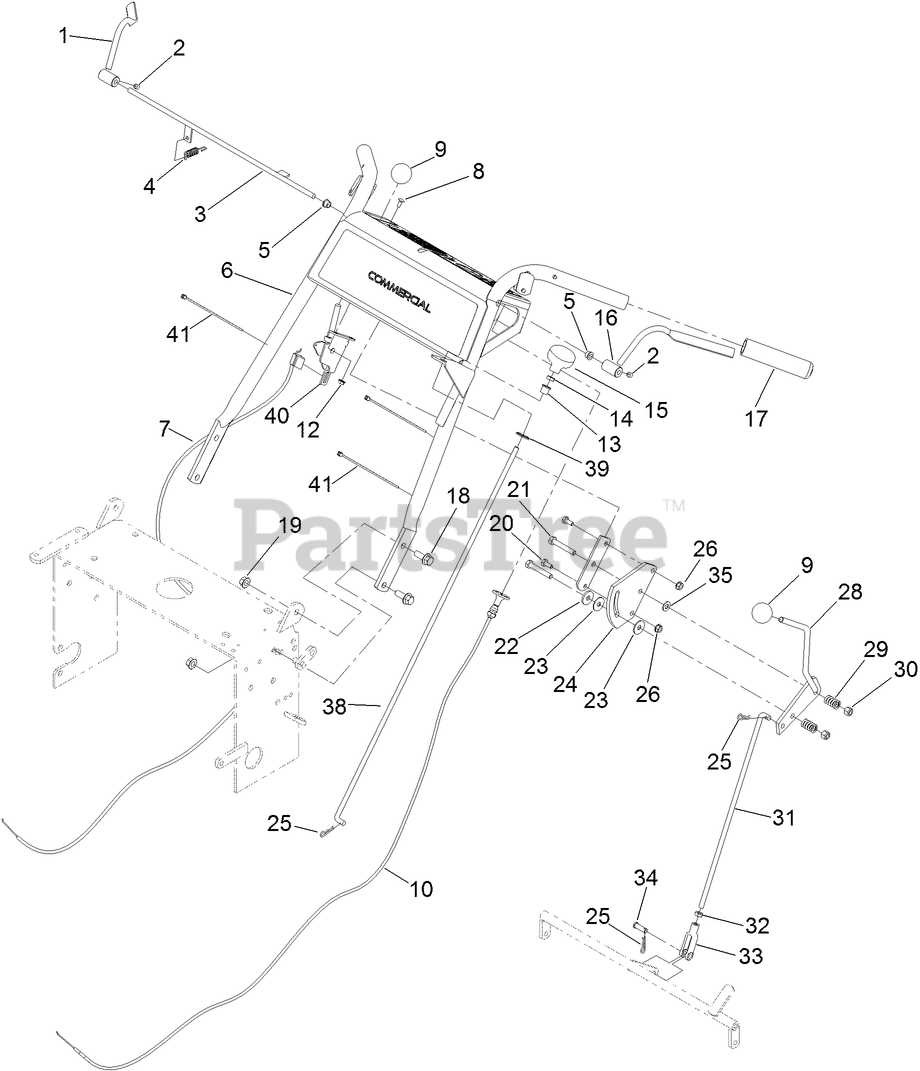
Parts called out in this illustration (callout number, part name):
1	RH OPERATOR PRESENCE CONTROL LEVER ASM
2	SCREW-SET
3	ROD-CONTROL, OPERATOR PRESENCE
4	SPRING-EXTENSION
5	BUSHING-NYLON
6	HANDLE ASM
7	CABLE-CONTROL
8	BOLT-CARR
9	KNOB-BALL
10	CONTROL, CHOKE
12	NUT-LOCK, FLANGE
13	Bearing-Nylon
14	NUT-JAM
15	Knob-Push / Pull
16	LH OPERATOR PRESENCE CONTROL LEVER ASM
17	GRIP-FOAM
18	SCREW-HHF
19	NUT-HF
20	SCREW-HH
21	SCREW-HH
22	Washer-Friction
23	Washer-Friction
24	PLATE-LEVER, SHIFTER
25	PIN-COTTER
26	NUT-HF
28	LEVER-SHIFT
29	SPRING-COMPRESSION
30	NUT-LOCK, NI
31	Rod-Control, Speed
32	NUT-JAM
33	YOKE-ADJUSTABLE
34	PIN-CLEVIS
35	WASHER-PLAIN
38	Linkage-Blade
39	NUT-PUSH
40	LEVER-CONTROL
41	TIE-CABLE
